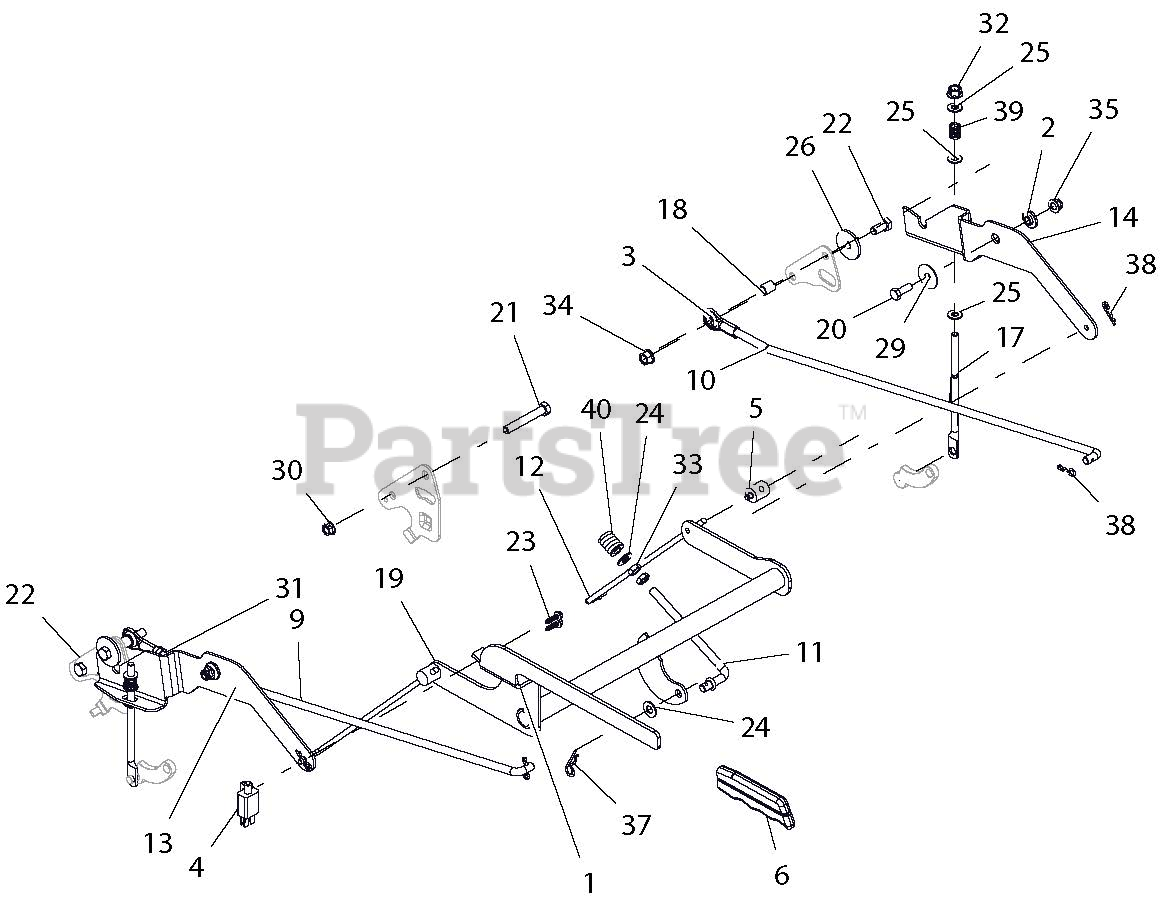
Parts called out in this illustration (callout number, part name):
1	WLDMT, BRAKE LEVER
2	BSHG, FLG .325X.499X.26X.88
3	ROD END, .38 RH
4	SWITCH- DOUBLE POLE N.O./N.O.
5	TRUNION, 1/4-20
6	GRIP, PARKING BRAKE (YELLOW)
9	STEERING, LINKAGE RH
10	STEERING, LINKAGE LH
11	LINK, OVER CENTER, PARKING BRK
12	LINK, BRAKE ARM
13	INTERLOCK, RH BRAKE LINK
14	INTERLOCK, LH BRAKE LINK
17	LINK, BRAKE COG
18	SPCR, SLV .385X.500X.652
19	E-RING, .250 X .025
20	BOLT-HEX.31-18X.875 YWZC GR5
21	@BLT-HEX .38-16X2.50 GR5 YWZC
22	@BLT-HEX .38-16X.75 GR5 YWZC
23	SCR-TAP #12X.75 BOSS INDHXHD
24	@WSHR-FL-STL.406X.812X.065 YWZ
25	@WSHR-FL-STL.344X.688X.065YWZC
26	WSHR-FL-STL .380X1.50X.125YWZC
29	WSHR-FL-STL .347X1.254X.048YWZ
30	@NUT-LK-CTR-FLG .31-18 YZ GR F
31	NUT-JAM .375-24 YWZC
32	NUT-LK-CTR-FLG .38-16 YWZC
33	NUT-HEX-JAM .375-16 YWZC
34	@NUT-LK-TOP-FLG .38-16 YWZC
35	@NUT-LK-NYL-FLG .31-18 YWZC
37	PIN-HAIR CTR .09 X 1.50 YWZC
38	PIN-HAIR INT .08X.18X1.18 YWZC
39	SPRING, COMPRESSION
40	SG-COMP .187X.56X1.62
